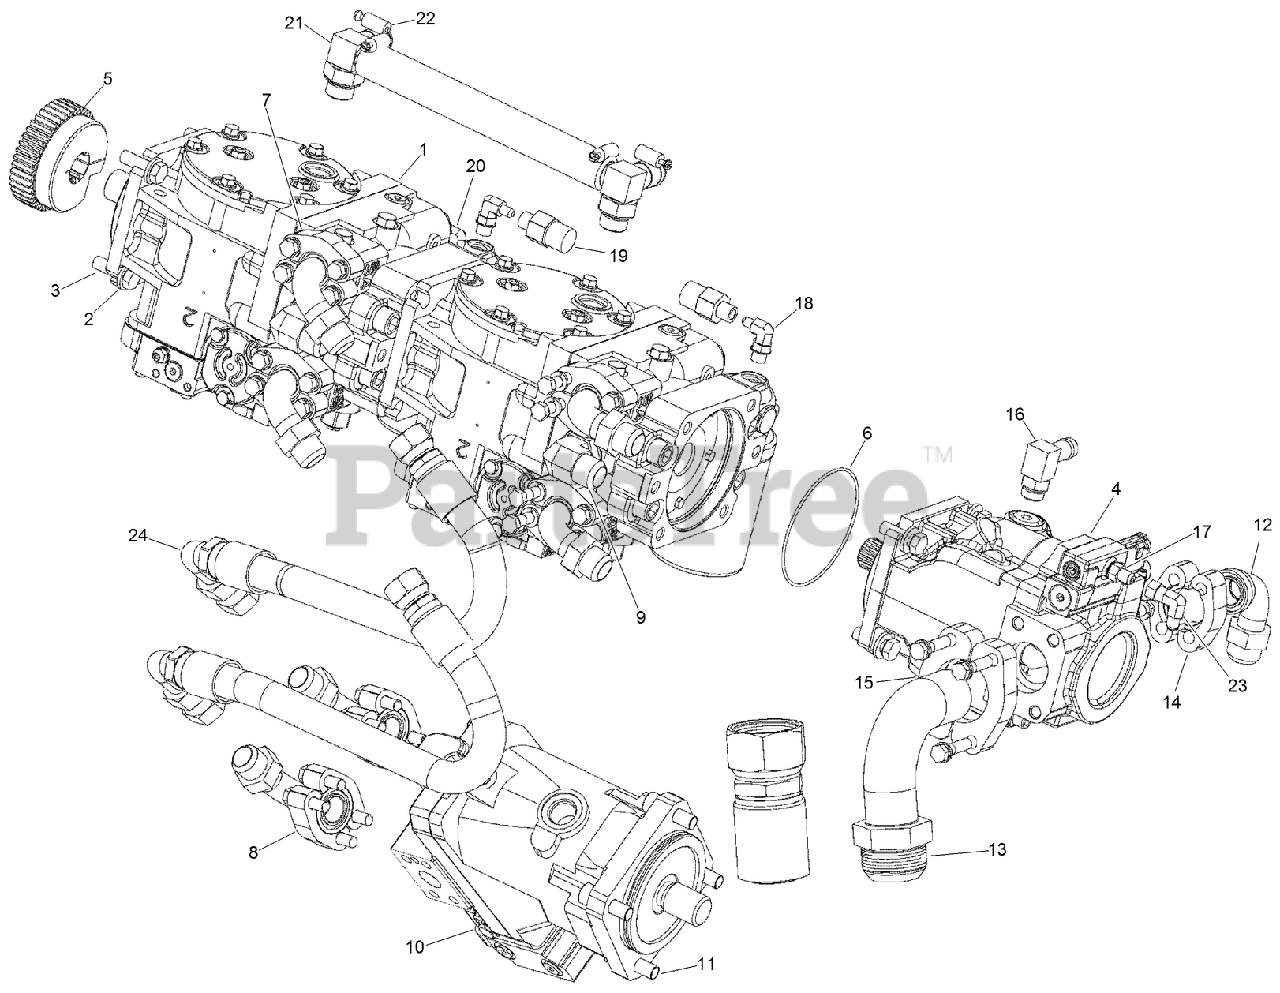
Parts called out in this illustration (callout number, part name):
1	TANDEM PUMP ASM
2	WASHER-FLAT
3	SCREW-HH
4	HYD PUMP ASM
5	HUB-COUPLER
7	FITTING-ELBOW
8	HYD FLANGE KIT
9	ELBOW-90 DEG
10	HYD MOTOR ASM
11	SCREW-HSH
12	ADAPTER-FLANGE, SPLIT
13	ADAPTER-FLANGE, SPLIT
14	FLANGE KIT
15	KIT, SPLIT FLANGE -16 Code 62
16	STEM - 90 Bead Hose 3/4 ID x 7.8 - 14
17	ADAPTER-STRAIGHT
18	ELBOW - 90 Degree, 9/16-18 flare x 1/4 inch PT
19	SWITCH-PRESSURE
20	ELBOW-90 DEG (ADJUSTABLE 37 DEG)
21	CONNECTOR
22	CLAMP - Hose HD Worm Gear 1.75 in w/Lin
23	ELBOW-SWIVEL, 90 DEG
24	KIT, Hydraulic Hoses
